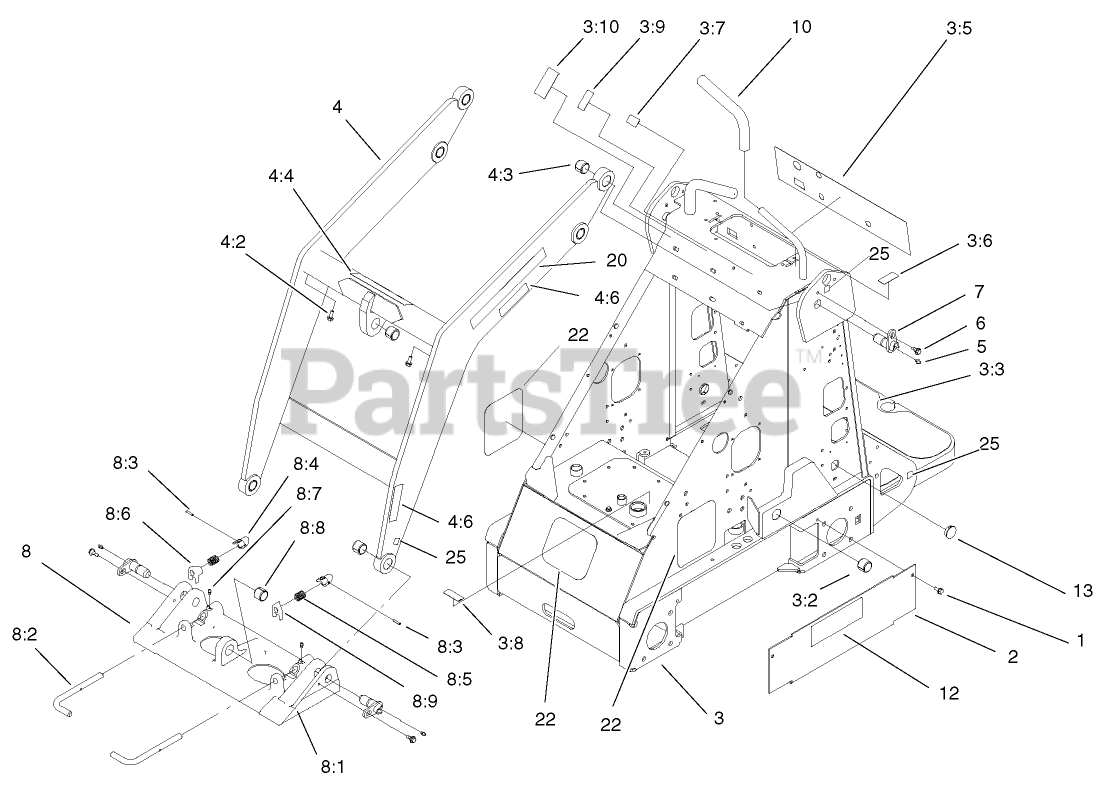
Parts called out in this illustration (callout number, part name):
1	SCREW-HWHTF
2	COVER-HOSE
3	FRAME ASM
3:2	BUSHING-TENSION
3:3	TREAD-FOOT
3:5	DECAL-PANEL, CONTROL
3:6	DECAL-THROTTLE
3:7	DECAL-LIMITER, SPEED
3:8	DECAL-OIL, HYD
3:9	DECAL-SELECTOR
3:10	DECAL-POWER, AUXILIARY
4	LOADER ASM
4:2	SCREW-HWHTF
4:3	BUSHING-TENSION
4:4	DECAL-CAUTION
4:6	DECAL-PINCH
5	FITTING-GREASE
6	BOLT-SHOULDER
7	PIN-PIVOT
8	QUICK ATTACH ASM
8:1	MOUNT-ATTACH, QUICK
8:2	PIN-LOCKING
8:3	PIN-GROOVED
8:5	SPRING-COMPRESSION
8:6	STOP-RH
8:7	FITTING-GREASE
8:8	BUSHING-TENSION
8:9	STOP-LH
10	GRIP-CUSHION
12	DECAL-4-PAW
13	PLUG-HOLE
18	DECAL-PANEL, CONTROL
20	DECAL - DINGO 320D
22	DECAL
25	DECAL-POINT, LIFT
